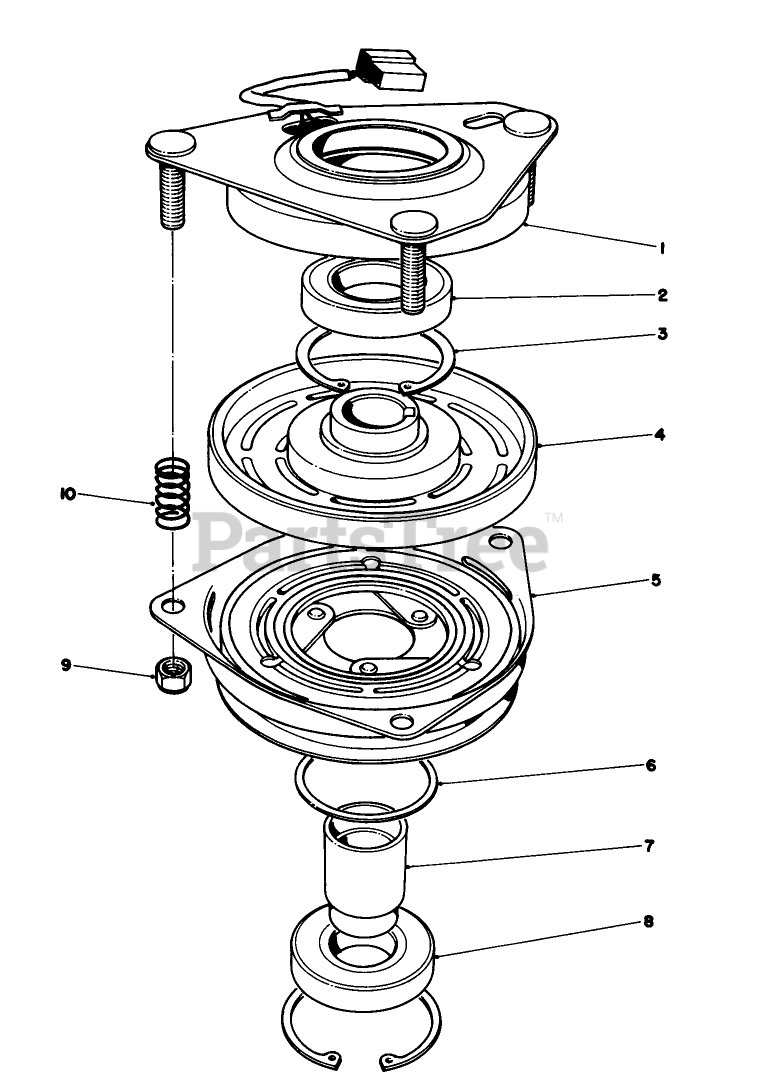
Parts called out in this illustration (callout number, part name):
1	FIELD BEARING ASM
2	BEARING-FIELD
3	RING-RETAINING
4	FIELD COIL/ROTOR BEARING ASM
6	SPACER-BEARING, PULLEY
7	COLLAR-BEARING
9	NUT-LOCK
10	SPRING
